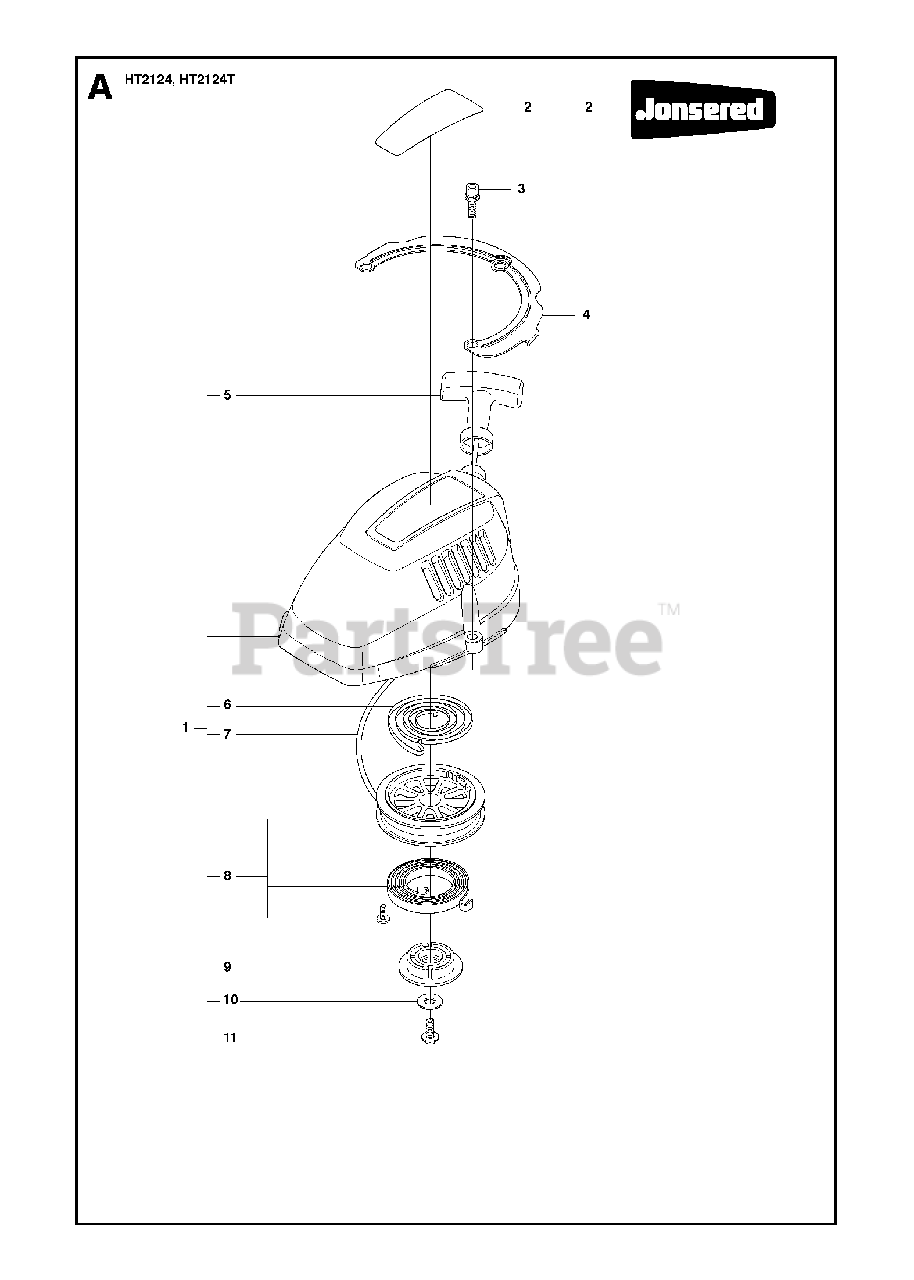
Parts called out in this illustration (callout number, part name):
6	RETURN SPRING
7	STARTER ROPE
8	STARTER PULLEY/SPRING ASSY
9	STARTER PULLY
10	WASHER
11	SCREW
